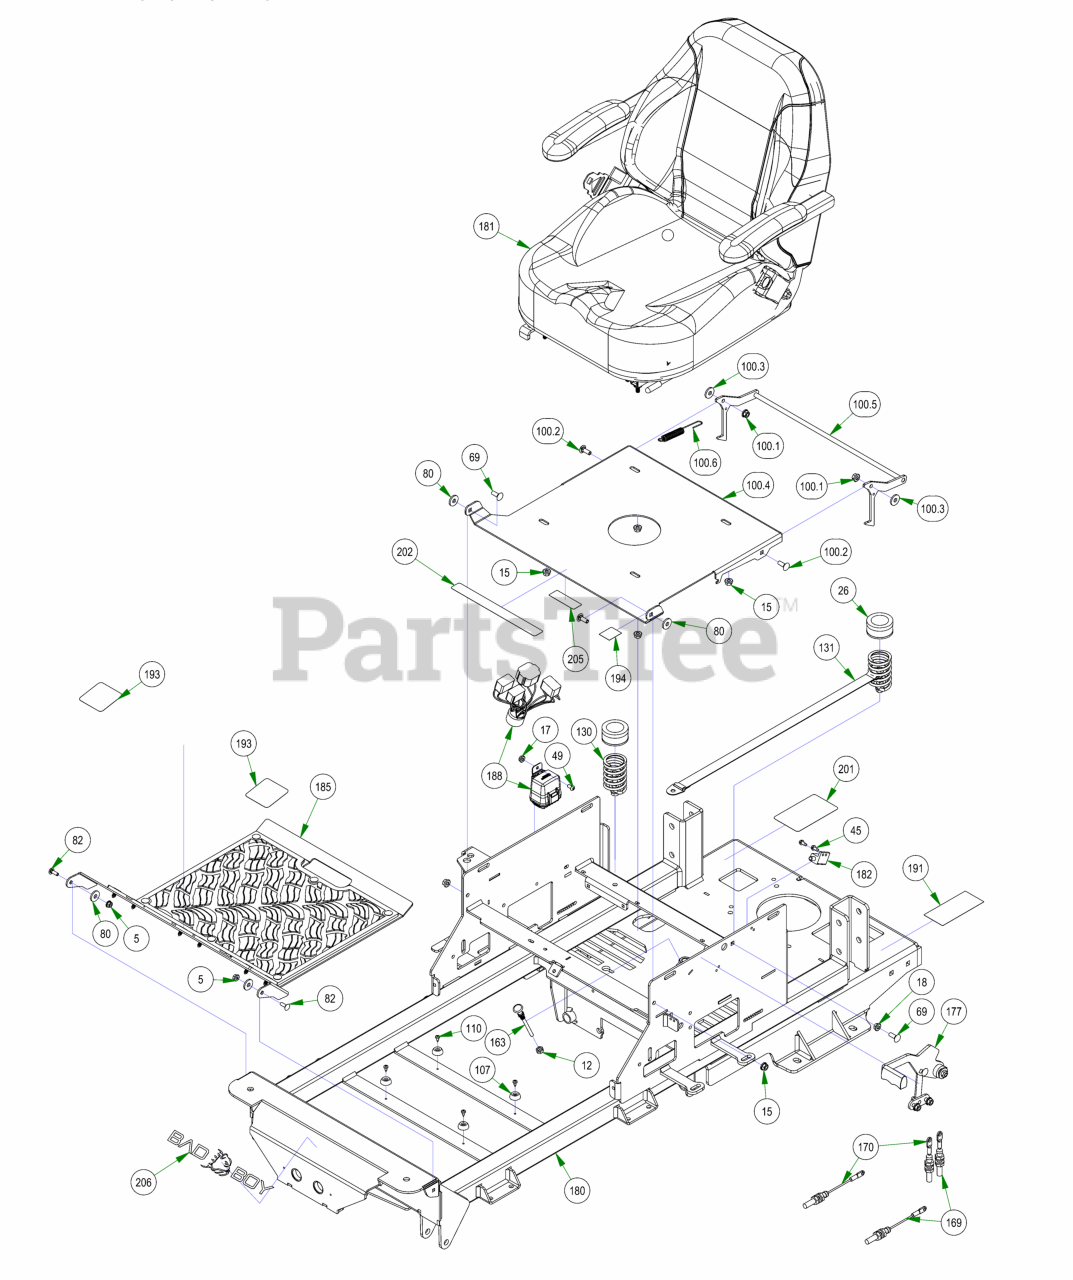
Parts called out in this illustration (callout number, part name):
5	1/4-20 NYL INSERT FLANGE LOCKNUT ZINC
12	3/8-24 HEX NUT ZINC YELLOW
15	5/16-18 NYLON INSERT FLANGE LOCKNUT ZINC
17	1/4-20 HEX SERRATED FLANGE NUT HARD/ZINC
18	5/16-18 HEX SERRATED FLANGE NUT HARD/ZINC
26	Seat Spring Cap Cover
45	12-24 X 1/2 HEX WASHER UNLSOT F TCS ZINC
49	1/4-20 X 1/2 BUTTON SOCKET CAP SCREW 18-8 STAINLESS STEEL
69	5/16-18 X 7/8 CARRIAGE BOLT ZINC
80	.360 ID X .983 OD X .120 THICK FLAT WASHER NYLON
82	1/4-20 X 3/4 CARRIAGE BOLT (GR.5) ZINC
99	2022 Maverick Rear Cover Assembly
100	MAVERICK/COMPACT OUTLAW SEAT PLATE ASSEMBLY
100.1	5/16-18 NYLON INSERT FLANGE LOCKNUT ZINC
100.2	5/16-18 X 7/8 CARRIAGE BOLT ZINC
100.3	.360 ID X .983 OD X .120 THICK FLAT WASHER NYLON
100.4	Seat Plate 2016
100.5	Seat Latch Rod Assembly
100.6	Brake Spring
107	Button Bumper
110	10-16 X 1/2 PAN PHIL TEK/3 CLIMASEAL OR ACF-SILVER COATED
130	Seat Spring Assembly
131	Seat Spring Assembly
169	2021 Load Balanced Brake Cable 1
170	2021 Load Balanced Brake Cable 2
177	2021 Load Balanced Brake Handle Assembly
180	2022 Maverick Frame - Painted
181	2022 Maverick Seat
182	Safety Switch
185	2021 Maverick Floorboard Assembly
188	Wiring Harness
191	2022 EPA Build Date Punch Label
193	2018 Maverick/2021 ZT Anti-Skid Steering Control Decals
194	2018 MZ/Magnum/ZT/MAV/Comp Out Brake Decal
201	Maverick Pump Belt Decal
202	Outlaw Warning Decal
205	Not For Sale In California
206	Flying Bulldog Front Bumper Decal
